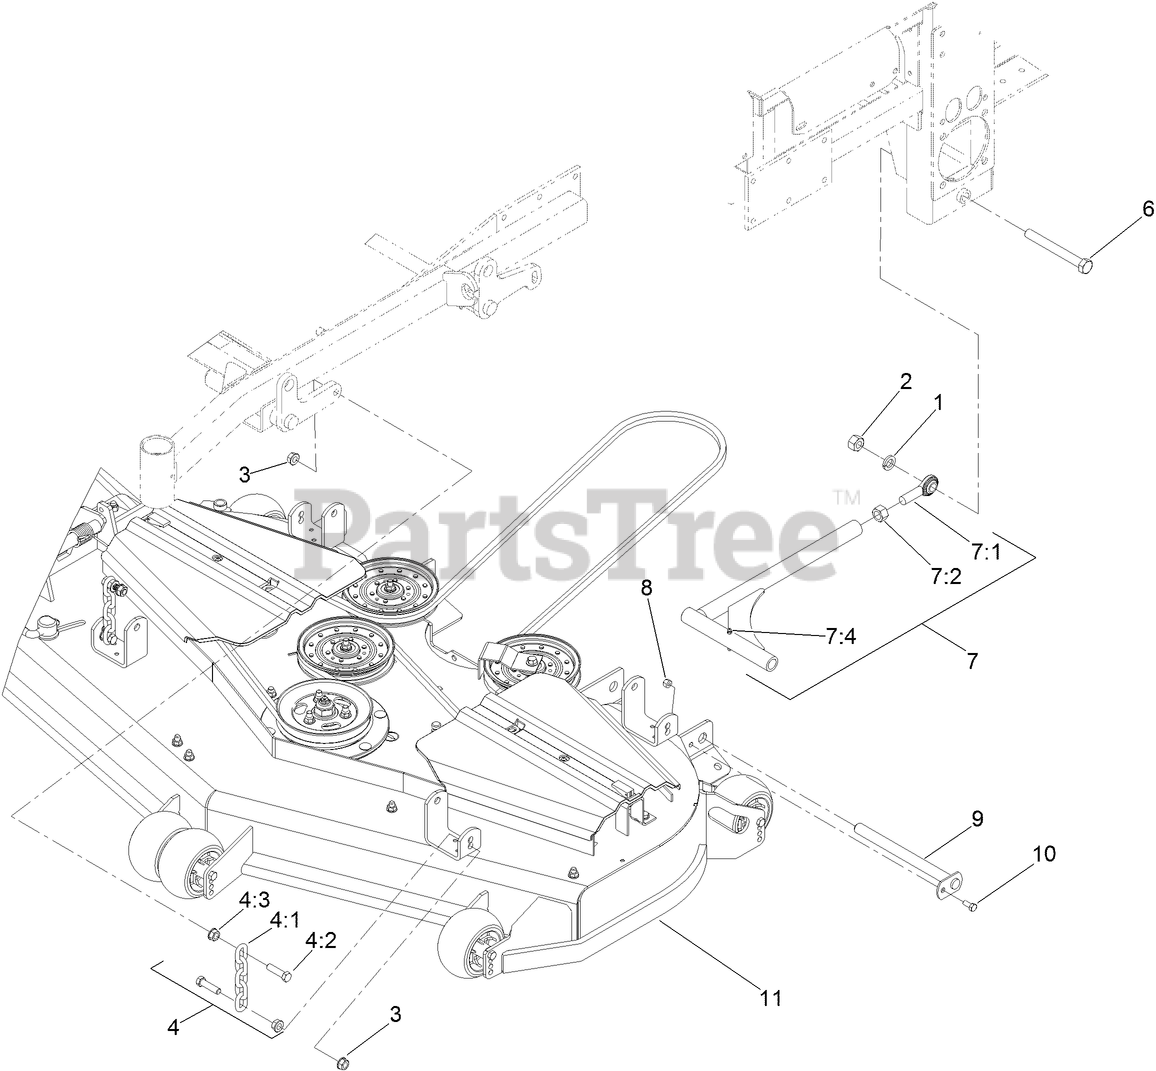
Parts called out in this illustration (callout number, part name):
1	WASHER-LOCK
2	NUT-HEX
3	NUT-HF
4	DECK CHAIN ASM
4:1	CHAIN-LIFT, DECK
4:2	SCREW-HH
4:3	NUT-HF
6	SCREW-HH
7	STRUT ASM
7:1	BALLJOINT-SPHERICAL
7:2	NUT-HEX
8	NUT-LOCK, NI
9	PIN-STRUT
10	SCREW-HH
11	DECK ASM
